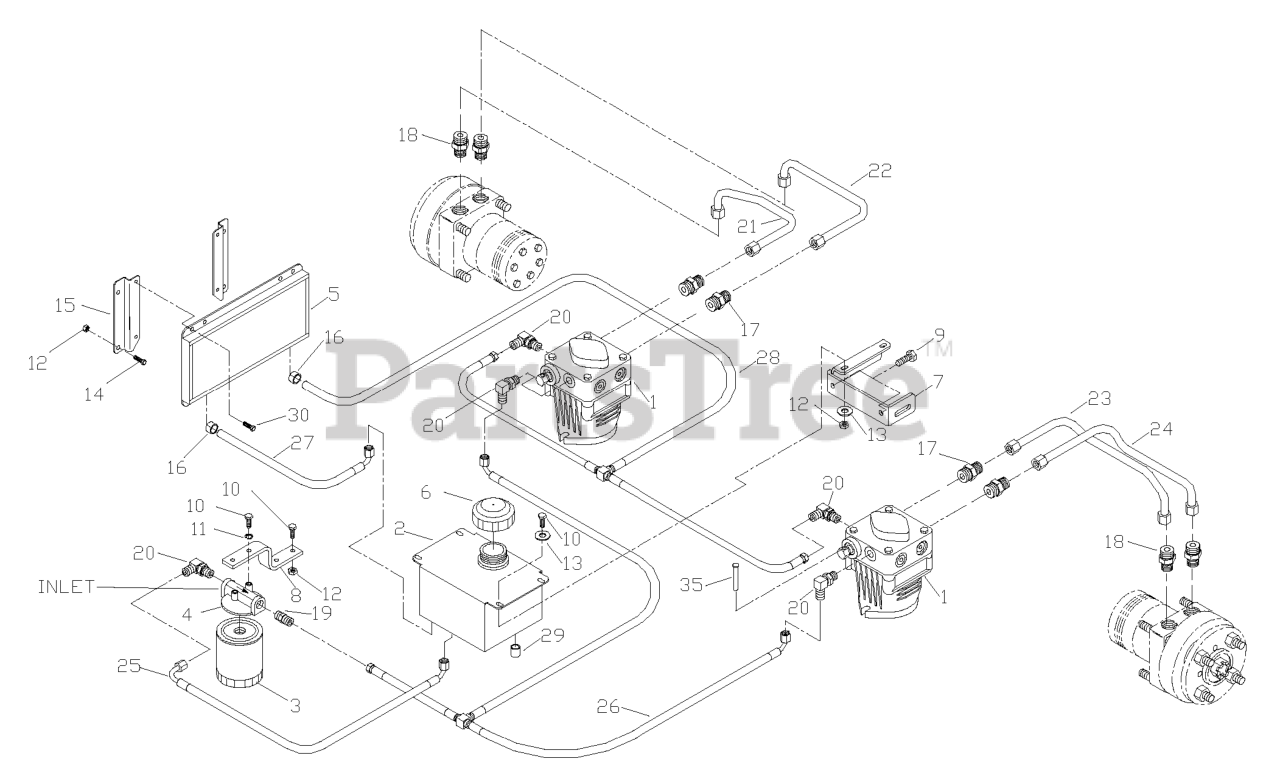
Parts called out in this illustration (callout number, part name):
1	PUMP
3	FILTER, OIL, NO VALVE
4	FILTER HEAD
6	HYDRAULIC CAP
7	TANK MOUNT LT
7	TANK MOUNT RT
8	FILTER MOUNT
9	HCS 5/16C X 3/4
10	HCS 1/4C X 3/4 HCS
11	LOCKWASHER 1/4"
12	NUT 1/4C CENTERLOCK
13	WASHER 1/4 FLAT
14	HCS 1/4C X 2
15	FRONT COOLER BRKT
15	COOLER BRACKET
16	HOSE CLAMP T-1865
17	FITTING, STRAIGHT F6400-8-8-0
19	STRAIGHT FITG
20	ELBOW, F6801-6-6-0 90 DEGREE
21	RUBBER HYDRAULIC HOSE (1)
22	RUBBER HYDRAULIC HOSE (1)
23	RUBBER HYDRAULIC HOSE (1)
24	RUBBER HYDRAULIC HOSE (1)
29	NUT 9/16-18 JIC CAP
30	HEX CAP SCREW 1/4
